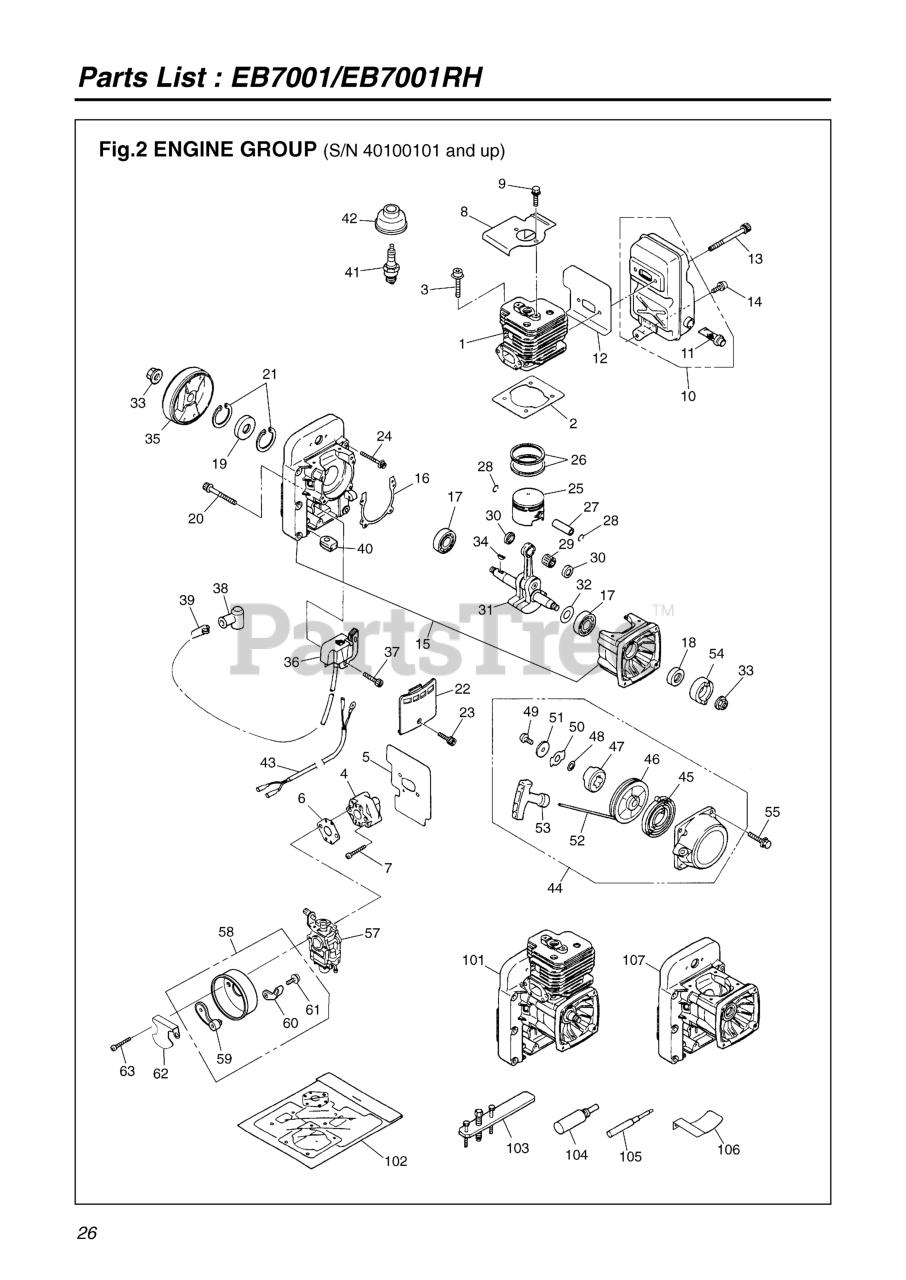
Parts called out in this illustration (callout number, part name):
1	CYLINDER (REPLACES 2750-12110)
2	GASKET, BASE
3	BOLT, M5 X 22
4	INSULATOR (REPLACES-13160)
5	GASKET
6	GASKET, CARB (RPLS -13131)
7	BOLT
8	COVER
9	BOLT, M5 x 10
11	ARRESTER
12	GASKET
13	BOLT, M6 X 70
14	BOLT, M6 X 12
15	CRANKCASE COMP
16	GASKET
17	BEARING
18	SEAL, OIL 15 X 25 X 7
19	OIL SEAL
20	BOLT, M5 X 30
21	SNAP RING
22	COVER
23	BOLT, M4 X 16
24	BOLT, M6 X 40
25	PISTON
26	RING
27	PIN, PISTON
28	RING, SNAP
29	BEARING
30	WASHER (RPLS 1491-41510)
32	SHIM (REPLACES 848-870-G000)
33	NUT, M10
34	KEY
35	ROTOR (REPLACES -71110)
36	COIL ASSEMBLY, IGINITION
37	BOLT, M4 x 20
38	CAP
39	SPRING
40	GROMMET
42	CAP
43	CORD COMP.
44	RECOIL ASSY
45	SPRING (RPLS -75220)
46	REEL
47	DOG
48	WASHER
49	SCREW
50	RETAINER (RPLS 1861-75161)
51	WASHER
52	ROPE
53	KNOB
54	PULLEY (RPLS -75210)
55	BOLT, M5 x 20
57	CARBURETOR (WYK-123-1)
58	CASE ASSY (RPLS -82400)
59	PLATE (RPLS -82420)
60	LEVER (RPLS -82430)
61	SCREW (RPLS- 82440)
62	PLATE
63	SCREW (RPLS 0263-30550)
101	SHORT BLOCK
102	KIT, GASKET
103	PULLER ASSY
104	STOPPER (TOOL) (RPLS 3320-9641
105	PULLER, PISTON PIN
107	CASE ASSY
